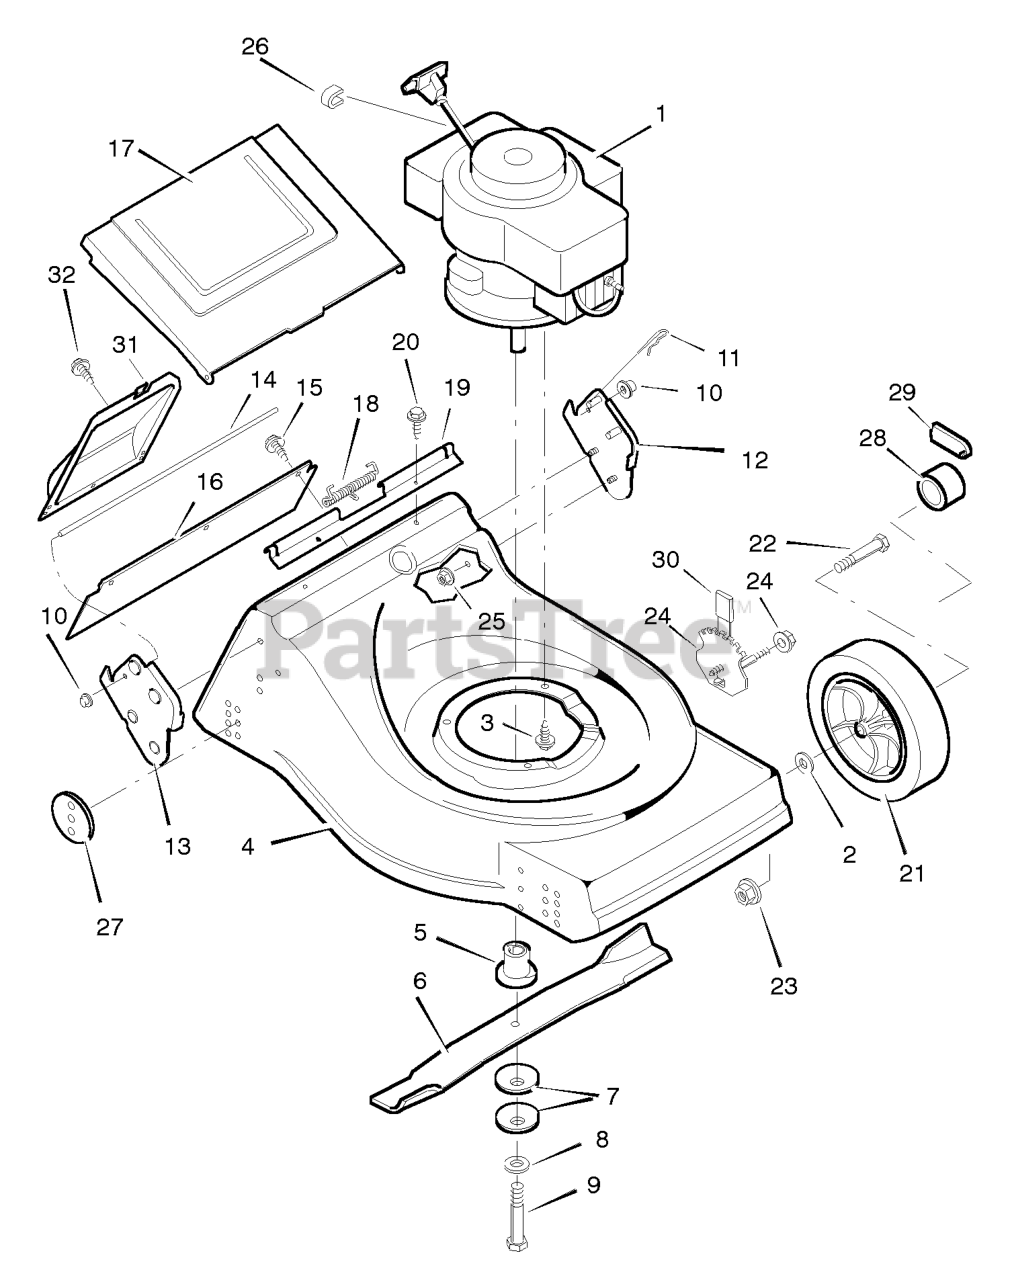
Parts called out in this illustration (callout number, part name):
1	Engine *
3	Bolt, Engine
4	Housing
5	Adapter, Blade
7	Washer, Belleville
9	Bolt, Hex
10	Push-On Cap
11	Pin, Hair
12	Bracket, Left Handle
13	Bracket, Right Handle
14	Rod, Door Pivot
16	Deflector, Rear (Model with Height Adjusters)
17	Door, Rear
18	Spring, Torsion
19	Spacer, Door
21	Wheel and Tire *
22	Bolt, Axle
23	Nut, Flange
24	Adjuster, Height
25	Nut, Flange
26	Stop, Rope
28	Hub Cap
29	Hub Cap
31	Cover, Rear
